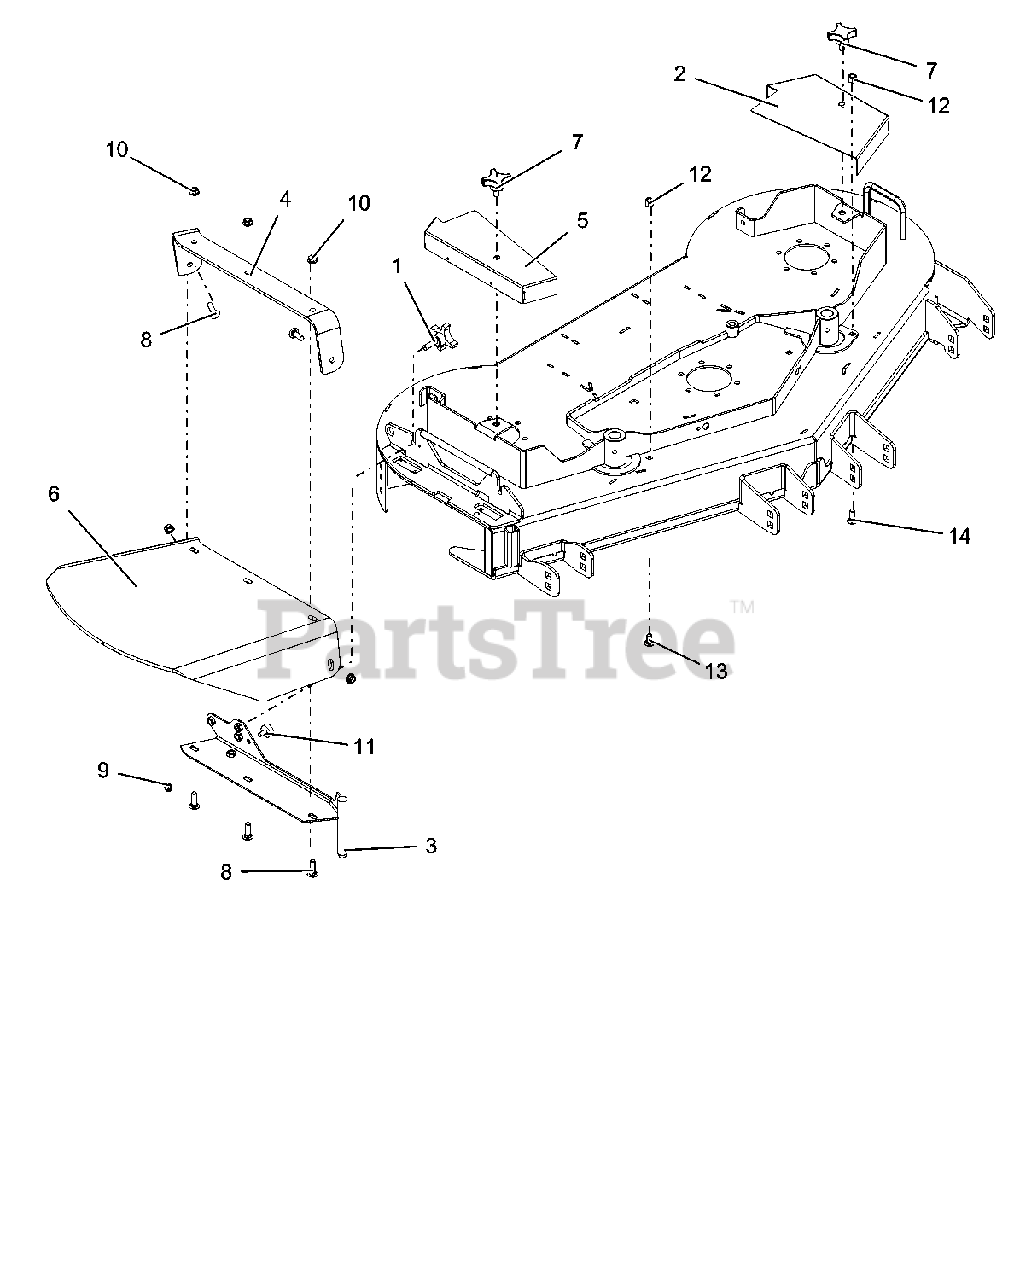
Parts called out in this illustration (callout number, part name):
1	KNOB, 3/8 X 1.25 - 4 PRONG
2	SHIELD, LH SPINDLE 52 FLWLK-RED
3	WLDT. DISCHARGE-RED
4	STRAP, WALK RUBBER DISCHARGE-RED
5	SHIELD, RH SPINDLE 52 FLWLK G2-RED
6	SHIELD, WALK RUBBER DISCHARGE
7	KNOB, 3/8-16 x .75
8	BLT-RDHDSQNK .38-16X1.25 G5 YWZC
9	@NUT-SPNLK-FLG .312-18 YWZC
10	@NUT-SPNLK-FLG .375-16 YWZC
11	BUMPER, RUBBER
12	NUT-LK-NYL .38-16 YWZC
13	BLT-RHDSSQNK .38-16X.75 G5YZ
14	BLT-RDHDSHSQNK.38-16X1.0 G5YZ
